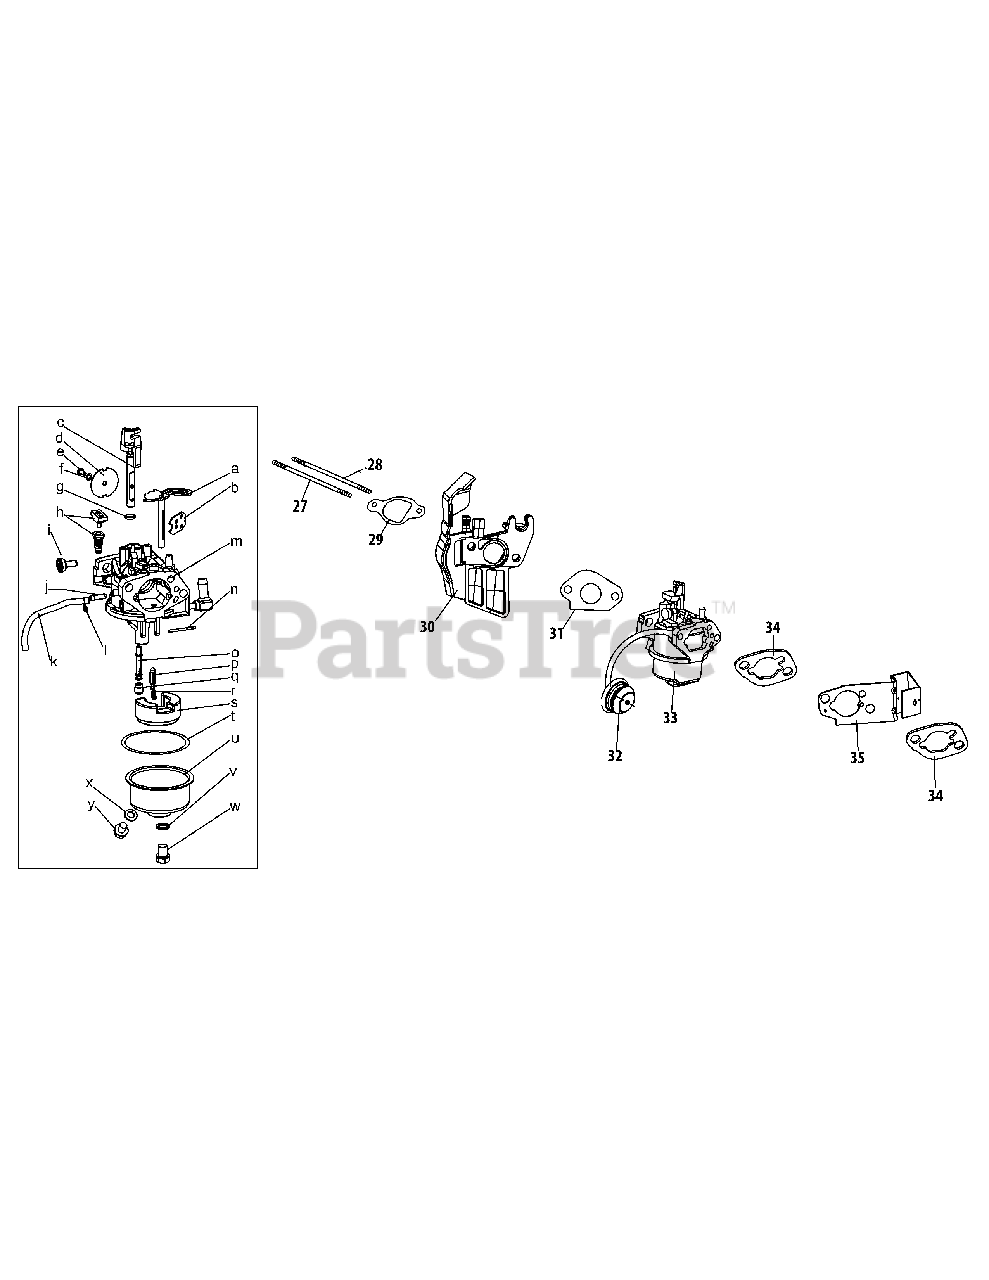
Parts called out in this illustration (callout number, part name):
27	Stud M6×117
28	Stud M6×105
29	Carburetor Insulator Gasket
30	Carburetor Insulator
31	Carburetor Gasket
32	Primer Assembly
32	Primer Bulb
33	Carburetor Assembly
34	Carburetor Gasket Plate
35	Choke Control
